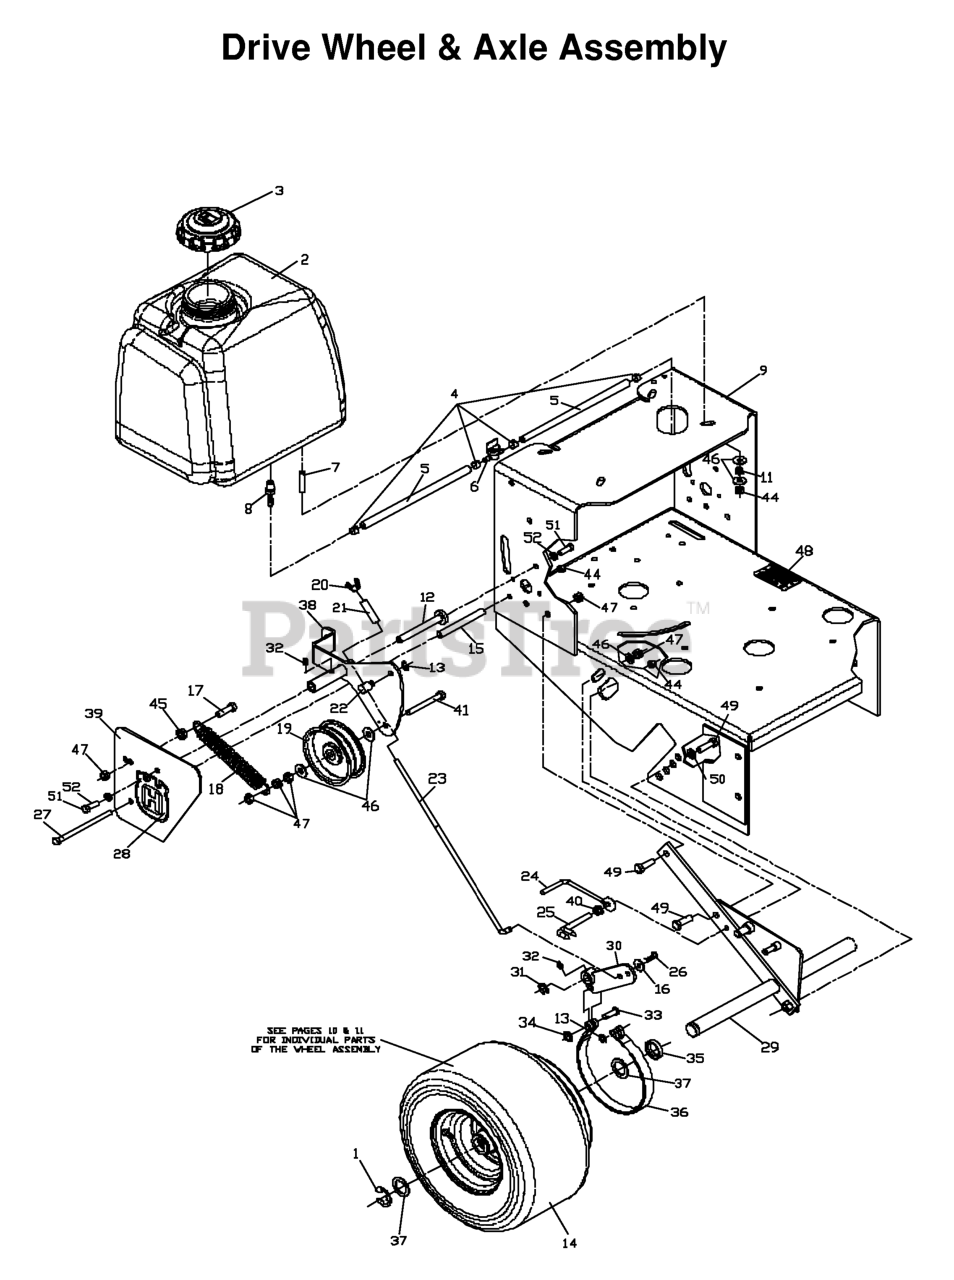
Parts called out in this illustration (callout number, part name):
1	E-RING 1"
3	FUEL CAP ANTI-SPLASH
4	HOSE CLAMP
5	GAS LINE 10"
6	FUEL VALVE
7	STUD, 5/16C
8	HOSE BARB 90 DEGREE
9	REAR DECK W/DECALS
10	DECAL, W3613
12	SHOULDER PIVOT TUBE
13	E RING 3/8"
14	WHEEL PARTS KIT
15	SPACER, LONG
16	WASHER 5/16 FLAT
17	HCS 3/8C X 1 1/4 GR5
19	PULLEY, IDLER
20	WINGNUT, 5/16C NYLOC
24	BELT GUIDE
25	SCRAPER (36 & 48)
26	HAIRPIN #2
27	HCS 5/16C X 5
28	DECAL, CRN H 3-1/8 SILVER
30	BRAKE ARM, RIGHT
31	E-RING 1/2 (2 2)
32	ZERK
33	CLEVIS PIN
34	NUT 3/8 PALNUT RTNG BLK PHOS
36	BRAKE BAND
37	MACHINE BUSHING
38	IDLER ARM - RH
40	NUT 5/16C WHIZ
41	TAPBOLT, 3/8C X 3
42	NUT 1/4C CENTER LOCK
43	HCS 1/4C X 1
44	NUT 5/16C CENTERLOCK
45	NUT 3/8C WHIZ
46	WASHER 3/8 FLAT
47	NUT 3/8C CENTERBLOCK
48	DECAL, PROP. 65
49	HCS 3/8-16X1.GRD.5.ZD
50	SLW 3/8 STD
51	HCS 5/16C X 1
52	WASHER.LOCK.HVY.HLCL.SPR.5/16
539106031	IDLER ARM LH
539111066	DECAL W4815
